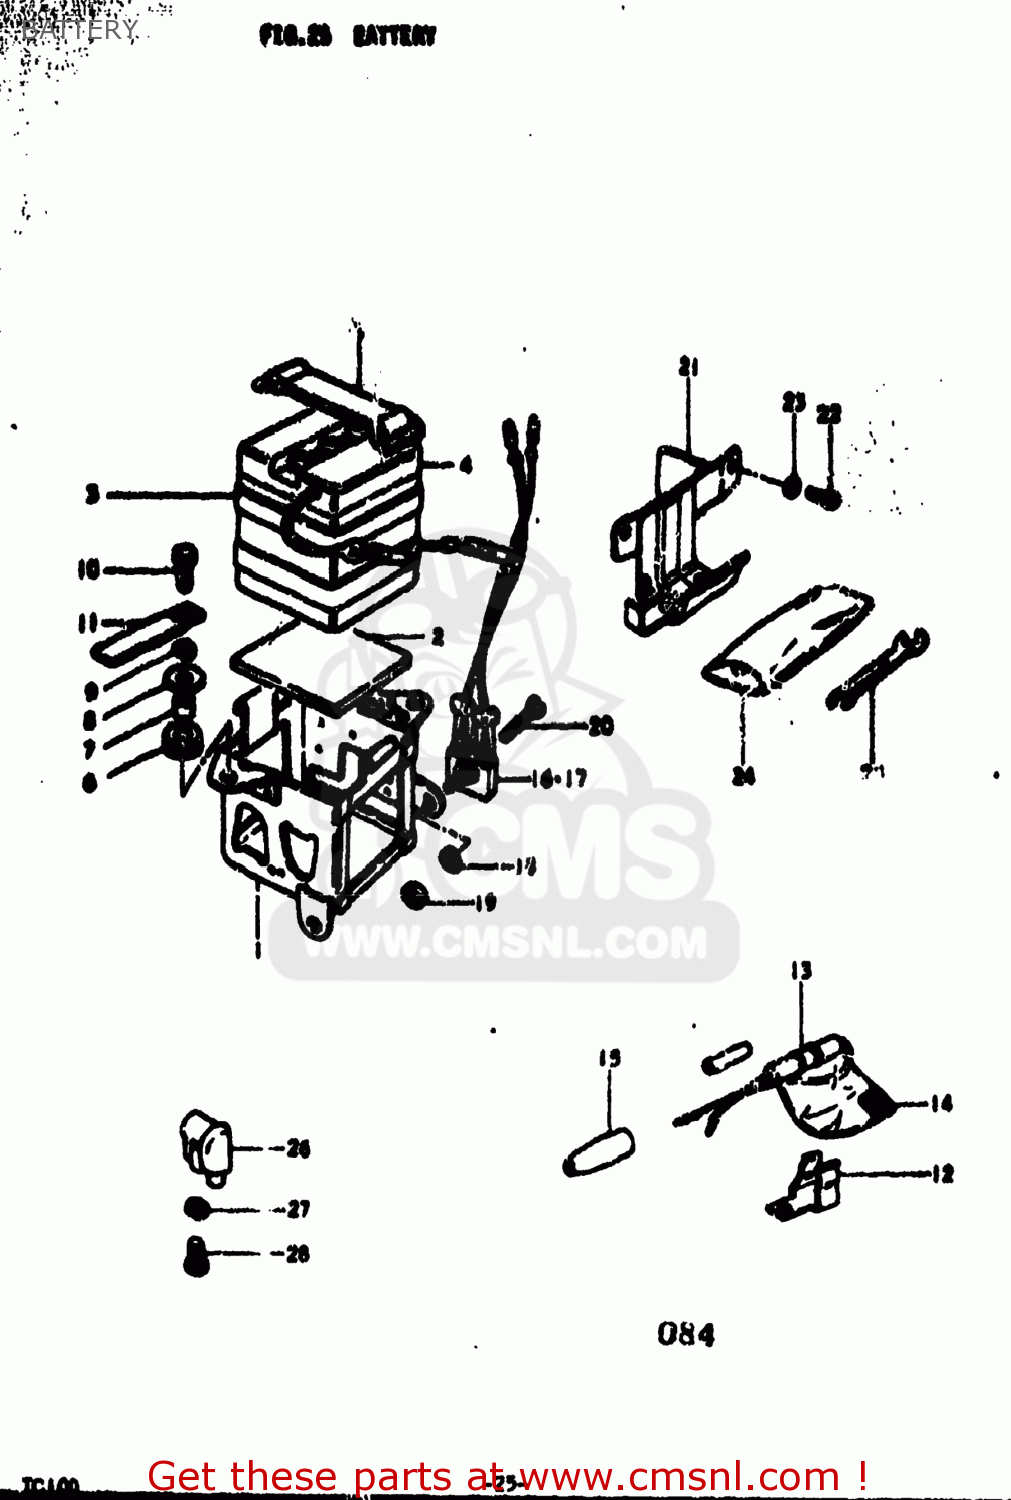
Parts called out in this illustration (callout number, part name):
1	HOLDER,BATTERY
2	CUSHION, BATTERY
3	PROTECTOR,BATTERY
4	BATTERY ASSY(6N4-2A4.2AH)
5	BAND
6	CUSHION
7	SPACER (7X9X7)
8	NUT
9	LOCK WASHER
10	BOLT
11	CLAMP
12	HOLDER,FUSE CASE
13	BOX ASSEMBLY,FUSE
14	FUSE(15A)
15	SEAL,DUST(10X17X45)
16	RECTIFIER ASSEMBLY
17	RECTIFIER ASSEMBLY
18	LOCK WASHER
19	NUT
20	SCREW
21	HOLDER,TOOL
22	SCREW 6X12
23	LOCK WASHER
24	TOOL SET
25	WRENCH, CONTACT POINT
26	LOCK SET,STEARING
27	LOCK WASHER
28	Screw
